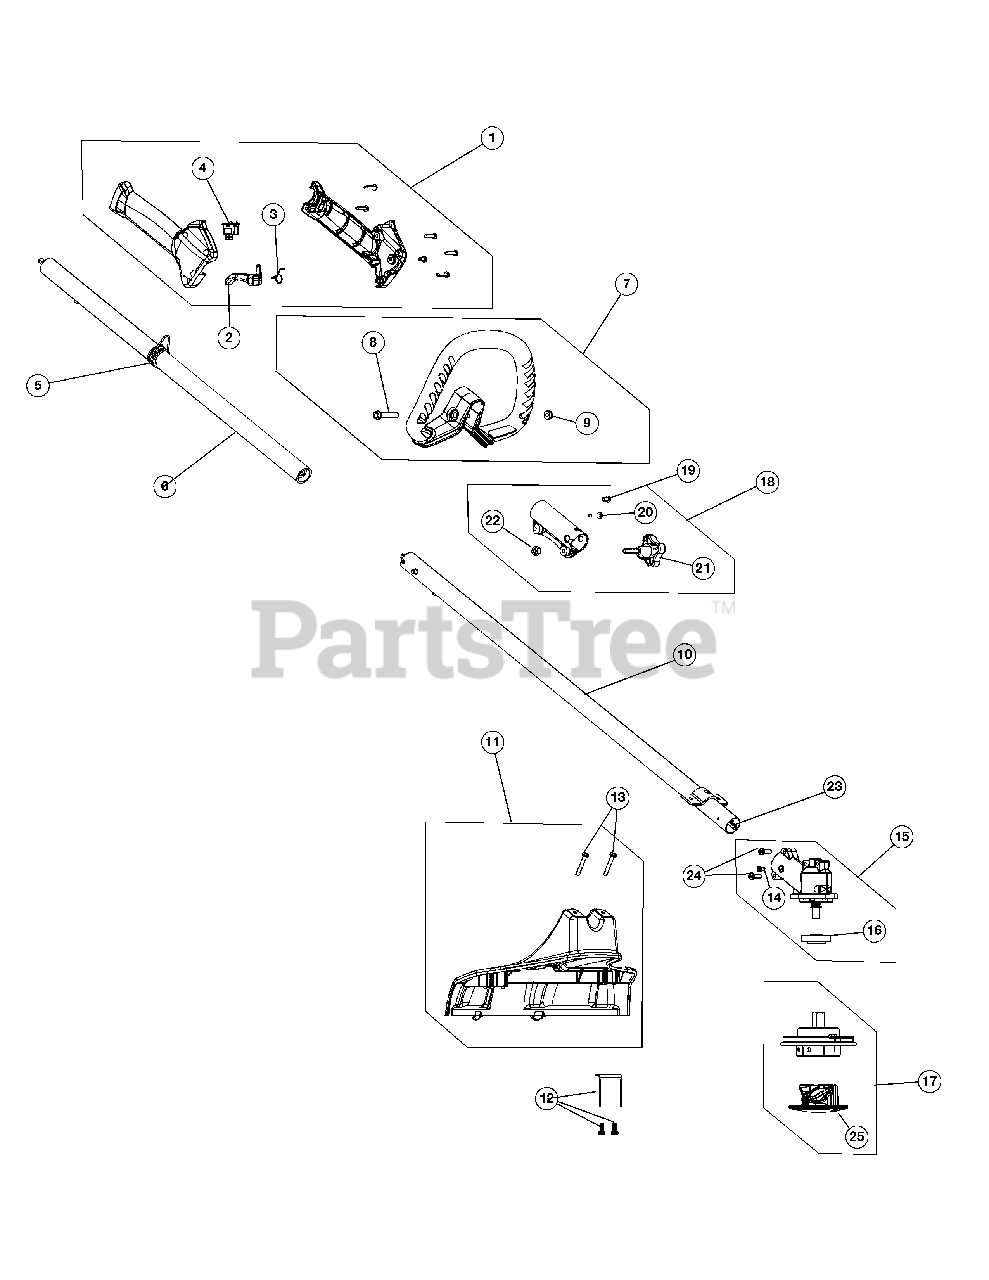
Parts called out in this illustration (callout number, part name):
1	Throttle Housing Assembly (Incl Ref No. 2-4)
2	Throttle Trigger
5	Shoulder Strap Clip
6	Upper Drive Shaft Housing Assembly
7	D-Handle Assembly (Incl Ref No. 8 & 9)
10	Lower Drive Shaft Housing Assembly
11	Shield Assembly (Incl Ref No. 12 & 13)
12	Blade Assembly
14	Anti-Rotation Screw
15	Gear Box (Incl Ref No. 14, 16 & 24)
16	Gear Box Spacer
17	Cutting Head Assembly (Incl Ref No. 25)
18	Split Boom Coupler (Incl Ref No. 19-22)
21	Adjustment Knob
22	Knob Retaining Nut
23	Lower Flexible Drive Shaft
24	Gear Box Screw
25	Cutting Head Cap
